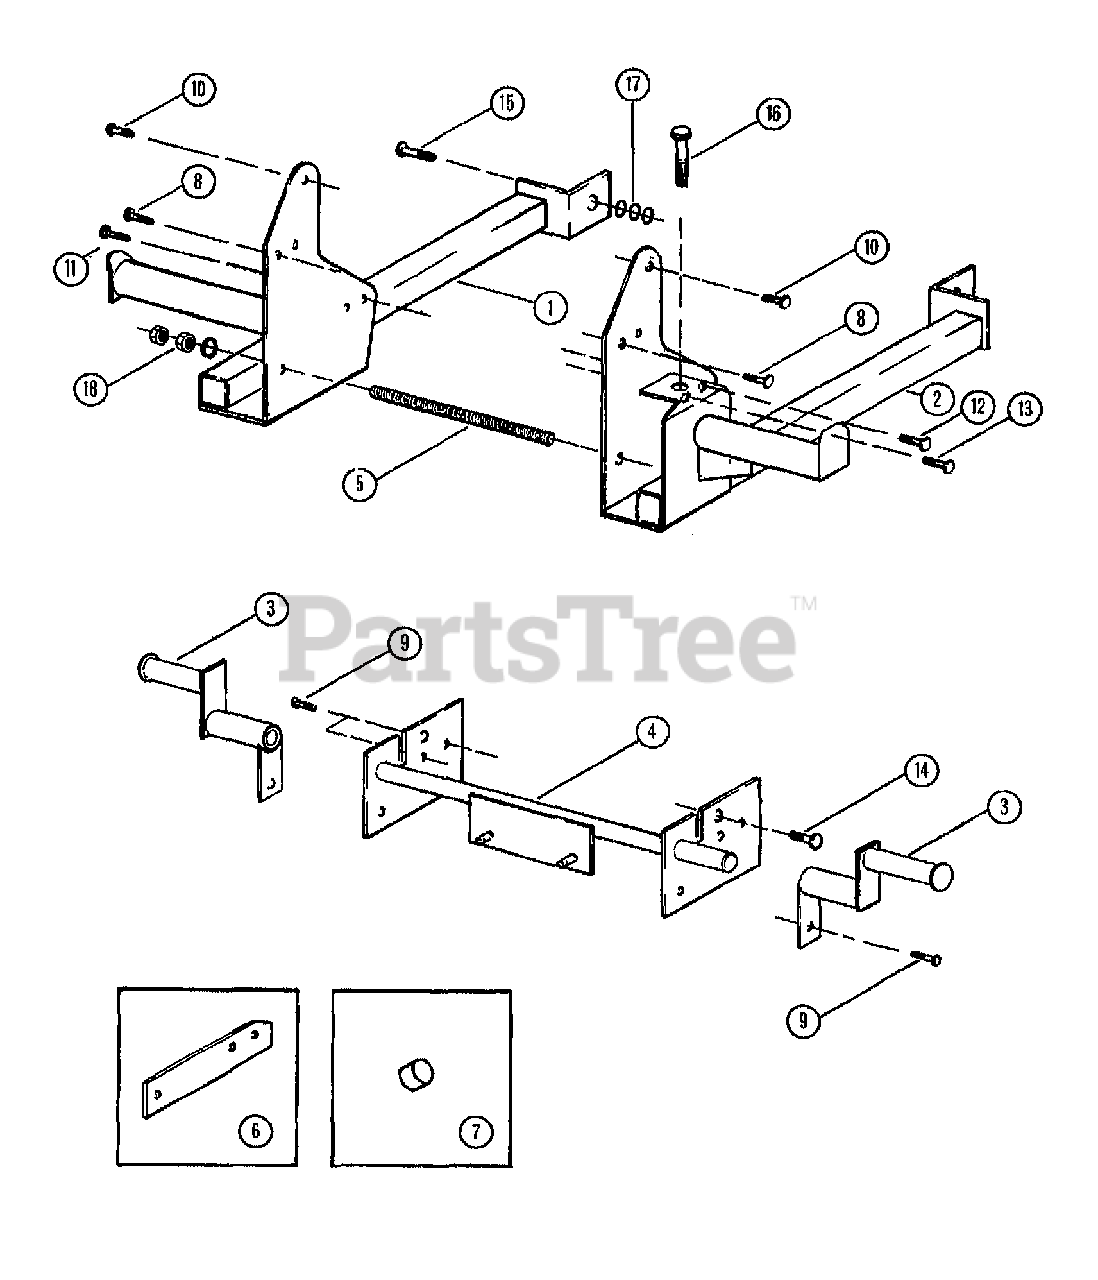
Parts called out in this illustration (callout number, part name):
1	MOUNT-RH REAR
2	MOUNT-LH REAR
3	MOUNT-FRONT
